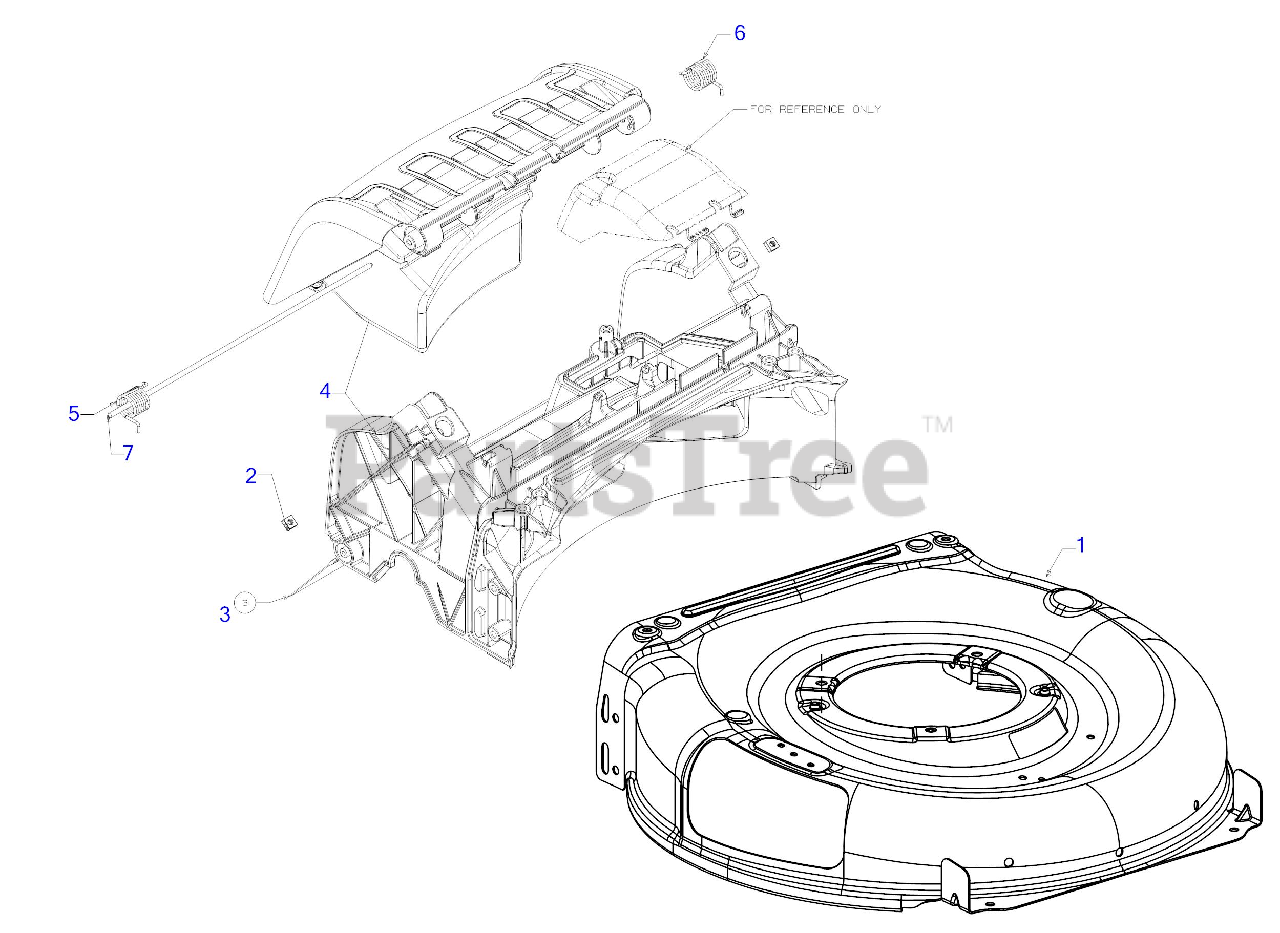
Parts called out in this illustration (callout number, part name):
2	SQUARE NUT 1/4-20
3	TRAILSHIELD
4	REAR BAG BAFFLE ASSEMBLY
5	TORSION SPRING (RH)
6	TORSION SPRING (LH)
7	REAR DOOR PIVOT ROD
